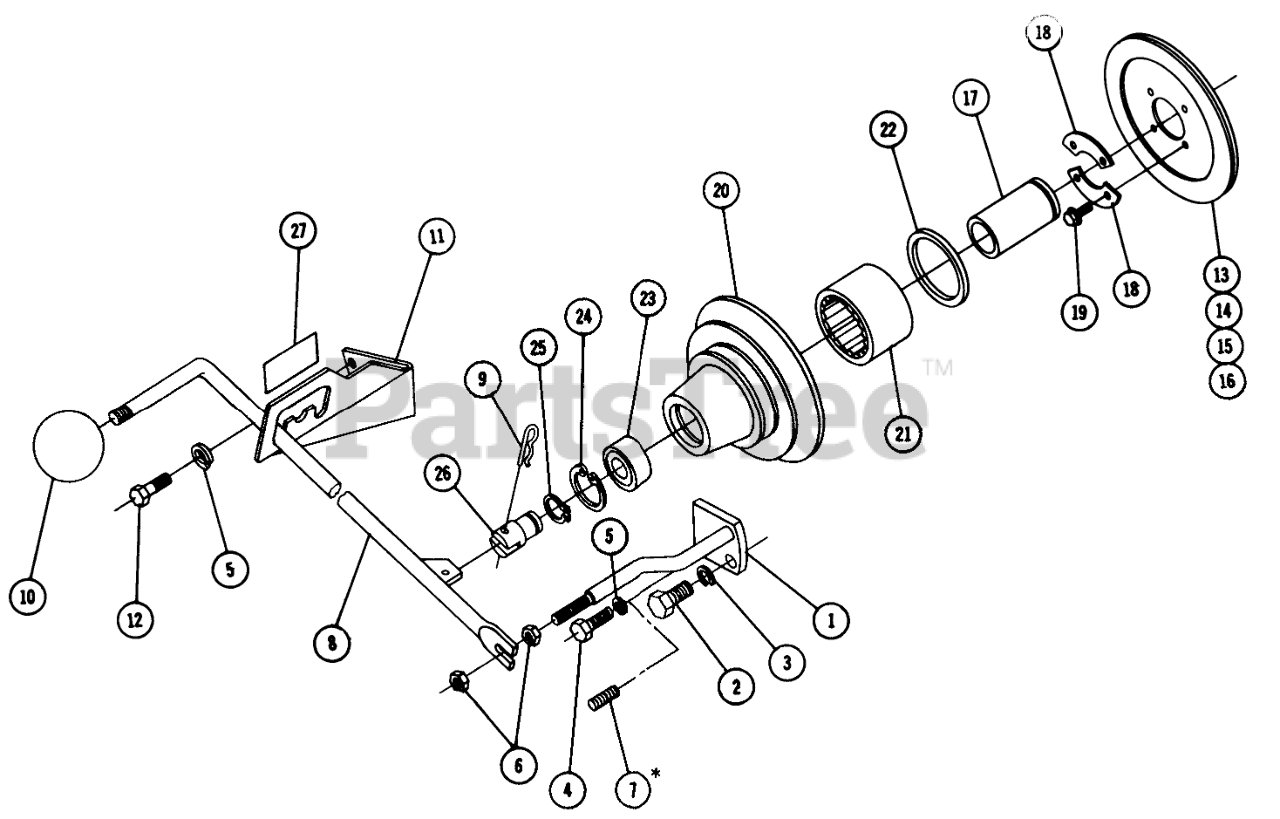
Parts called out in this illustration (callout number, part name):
1	PLATE & ROD ASSEM R
2	H H C S
3	LOCKWASHER
4	Bolt
5	Lockwasher
6	Nut
7	Set Screw 3/8-16 x 3/4 Nylok
8	ROD ASSY
9	Hairpin
10	Knob
11	Bracket
12	Bolt
13	L/A CLUTCHPLATE&FACI
14	Clutch Plate
15	CLUTCH FACING
16	RIVET-BRASS
17	RACE-BEARING
18	RETAINER
19	Screw
20	Clutch Housing
21	Seal
22	SEAL-OIL
23	Bearing
24	Ring-Snap
25	RING-SNAP, EXTERNAL
26	SHAFT
27	DECAL
